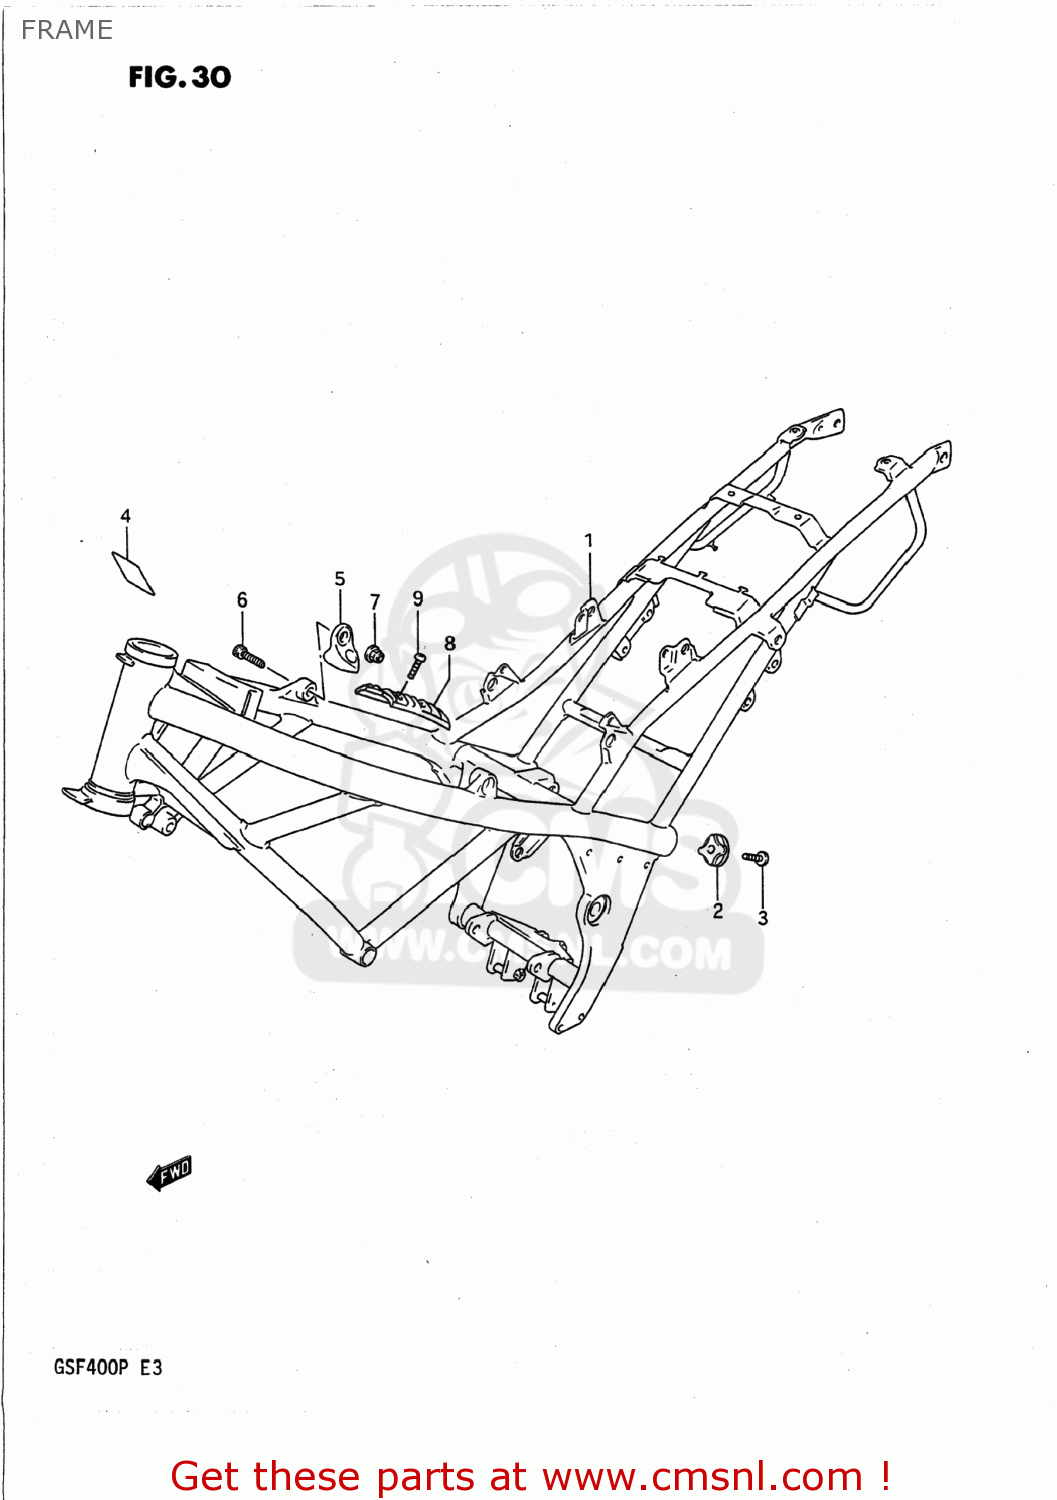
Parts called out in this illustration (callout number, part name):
1	FRAME
2	CAP,TANK RAIL END
3	SCREW
4	PROTECTOR,FRAME COVER FR
5	BRACKET,ENGINE MOUNT
6	BOLT, (10X30)
7	NUT
8	PROTECTOR,FUEL TANK,L
9	SCREW
